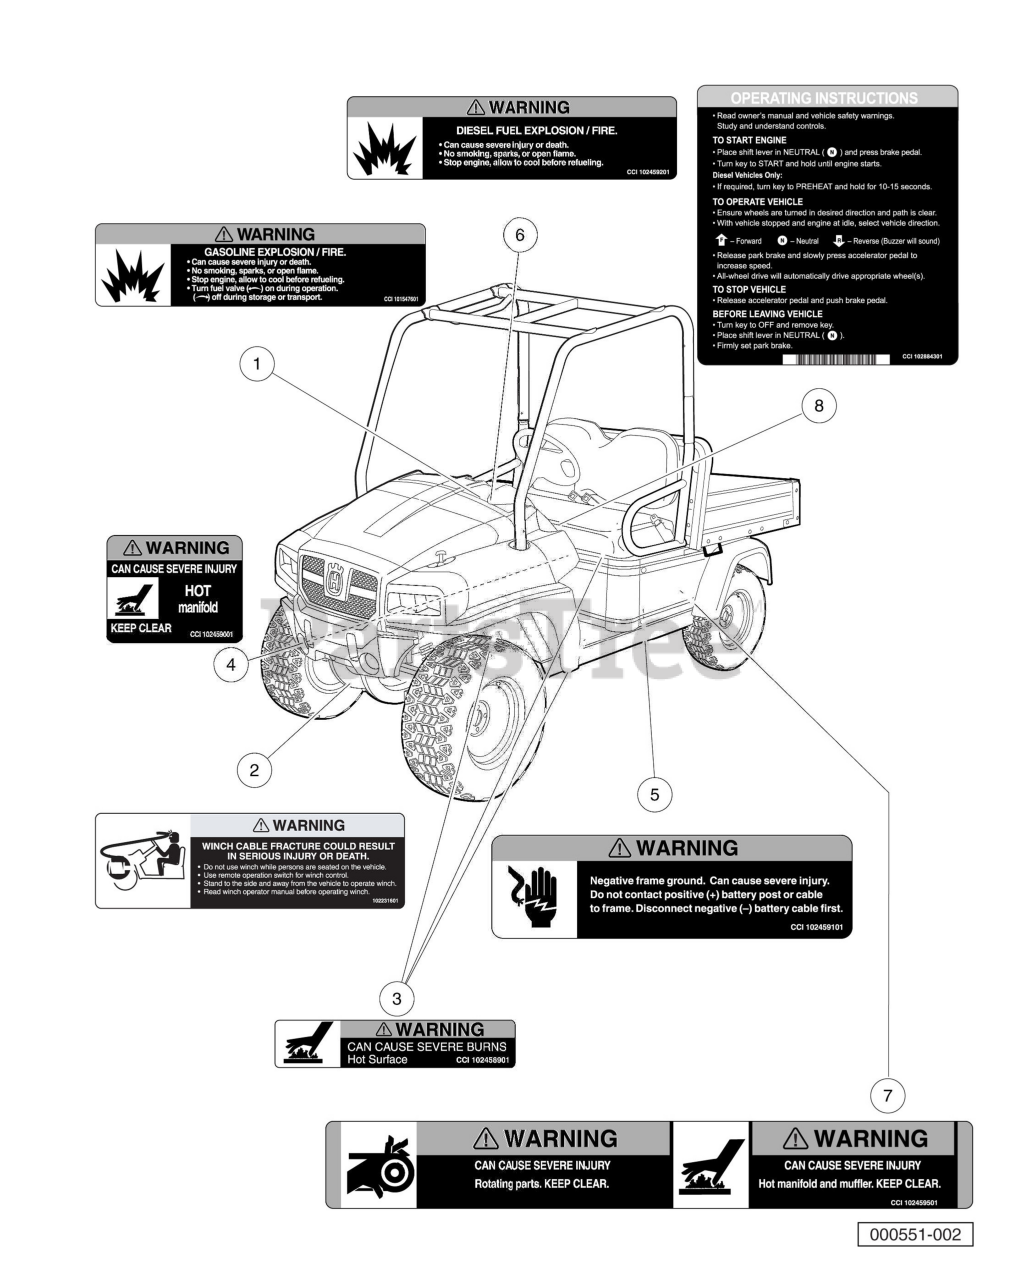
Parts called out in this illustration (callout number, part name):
1	Decal, Gasoline Explosion/Fire Warning
2	Decal, Winch Cable Fracture Warning
3	Decal, Hot Surface Warning
4	Decal, Hot Manifold Warning
5	Decal, Frame Ground Warning
6	Decal, Diesel Explosion/Fire Warning
7	Decal, Rotating Parts and Hot Exhaust Warning
8	Decal, Operating Instr, AWD
